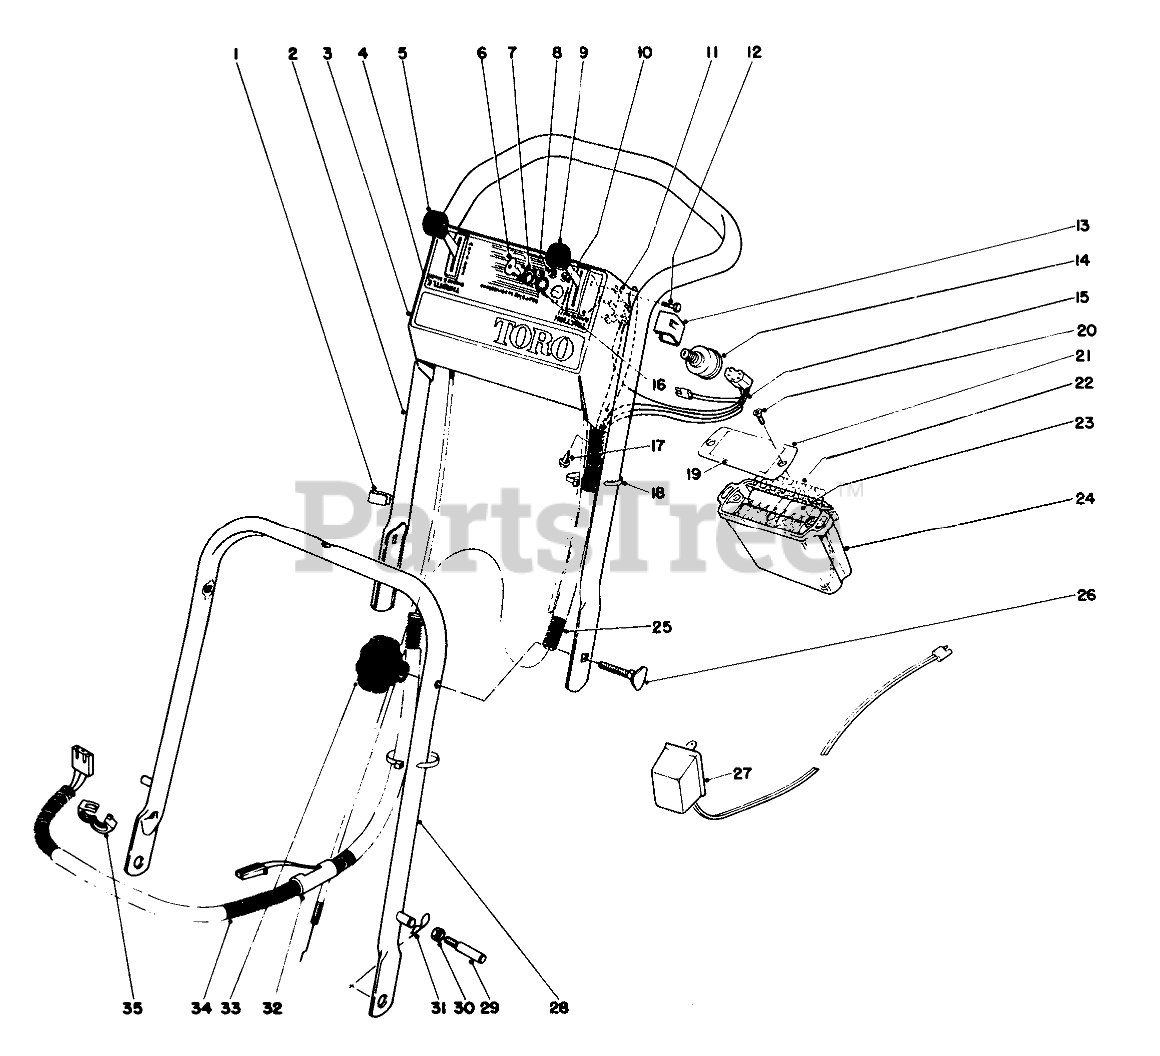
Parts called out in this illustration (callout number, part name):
2	UPPER HANDLE
3	Control Plate
4	Decal Control Plate
5	Control Throttle
6	Key
7	NUT-HH
8	NUT-HEX
9	Traction Control
10	WASHER-FLAT
11	CONTROL SWITCH
12	SCREW-HH
13	Cover Switch
14	SWITCH-STARTER
15	Wire Harness
16	WASHER-TOOTH, INTERNAL
17	SCREW-HWHTF
18	TIE-CABLE
19	Decal Battery
21	Cover
22	Spacer
23	Battery Pack Assembly (Incl. Ref. #19-22 & 24)
24	Container Pack
25	Cover Wiring Harnes Upper
26	SCREW-HANDLE
27	Charger
28	Lower Handle
29	HANDLE PIN
30	Nut
31	PIN-COTTER, HAIR
32	Breakout Fitting
34	Cover Wiring Harness Lower
35	RING FITTING
